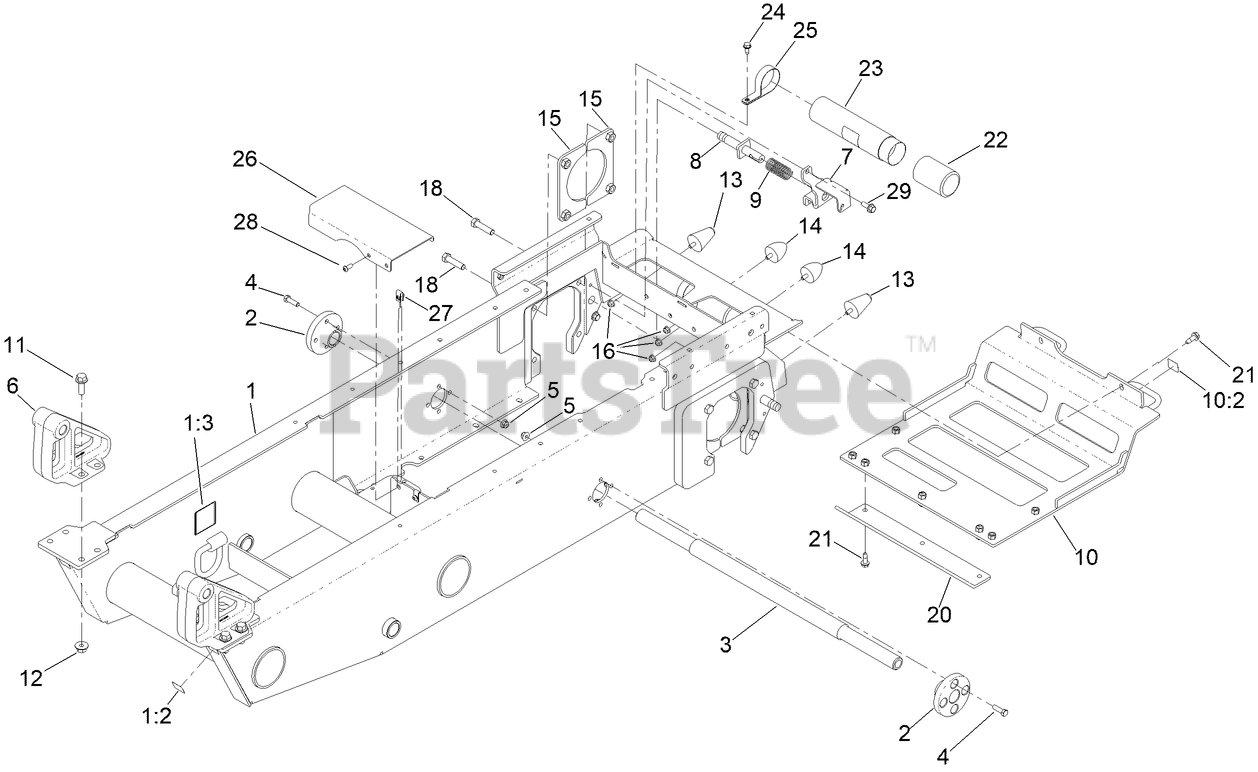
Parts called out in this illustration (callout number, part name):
1	FRAME ASM- STRAIGHT
1:2	DECAL-LIFT HERE
1:3	DECAL-TIEDOWN
2	HUB-MOUNT, TRACK
3	SHAFT-TRACK
4	SCREW-HH
5	NUT-HF, NI
6	PIVOT-DUMP (MACHINED)
7	BRACKET-BRAKE ASM
8	SHAFT-BRAKE
9	SPRING-COMPRESSION
10	PLATE-SIDE
10:2	DECAL-TIEDOWN
11	SCREW-HHF
12	NUT-LOCK, FLANGE
13	BUMPER-RUBBER
14	BUMPER-RUBBER
15	HYDRO MOUNTING PLATE ASM (WELDED)
16	NUT-HF, NI
18	SCREW-HH
20	PLATE-SKID
21	SCREW-TAPPING
22	CAP-HOUSING
23	TUBE-MANUAL
24	SCREW-HWHTF
25	CLAMP-R
26	BRACKET, MANIFOLD SHIELD
27	NUT-CLIP, U
28	SCREW-HSBH
29	SCREW-HHF
